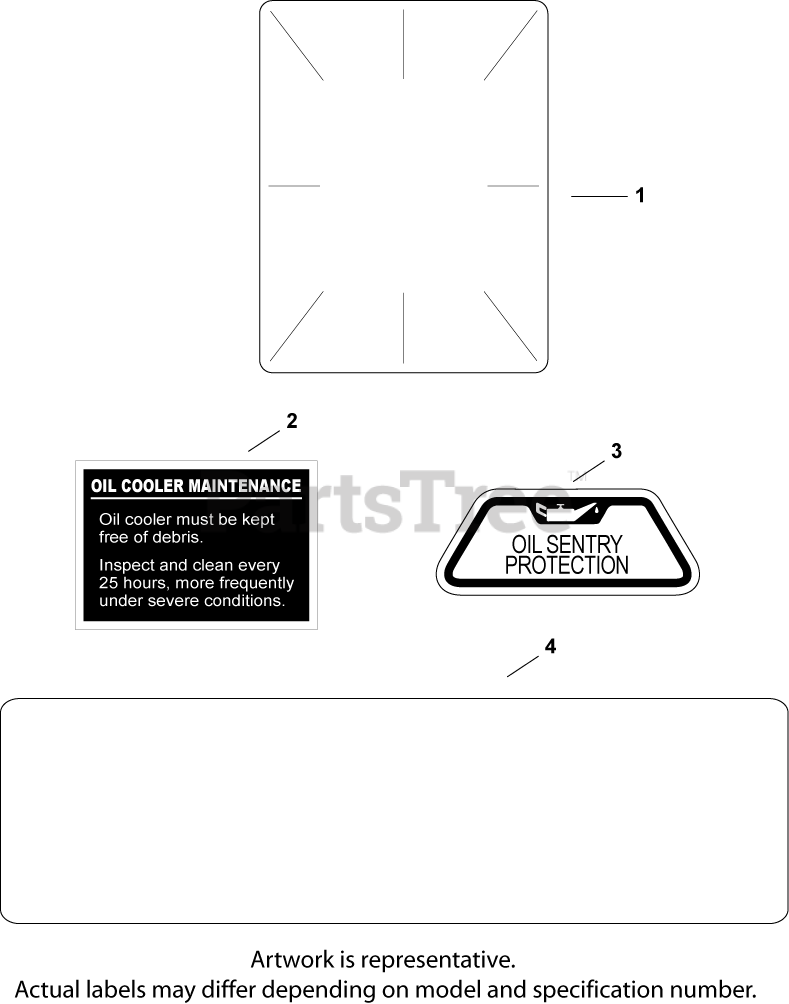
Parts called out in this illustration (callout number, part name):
1	DECAL, CLEAR LAMINATE USE 25 113 70-S
2	DECAL, OIL COOLER - (#DSC)
3	DECAL, OIL SENTRY - (#DSC)
4	DECAL, COMMAND 27 HP
